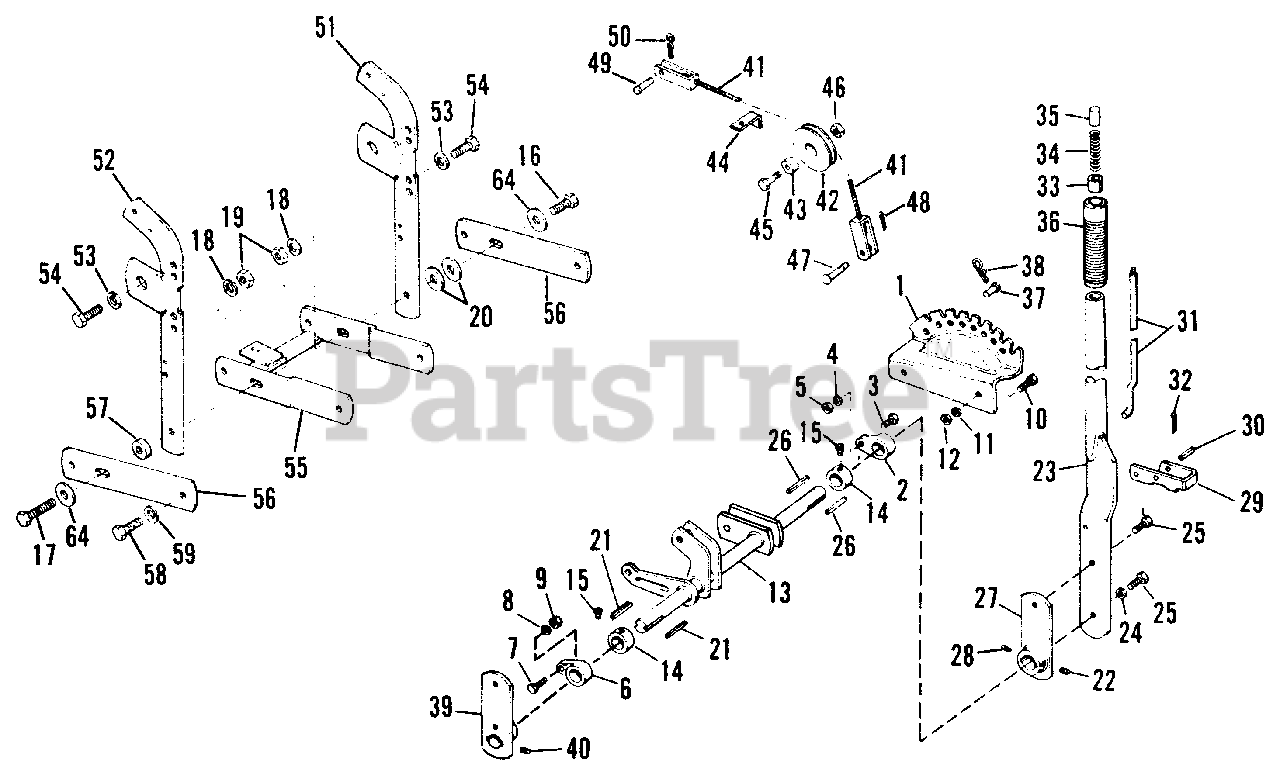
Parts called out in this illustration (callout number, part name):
1	Lift Lever Quadrant
2	Lift Lever Bearing
3	Hex Capscrew, 5/16"-18 x 1-1/4"
4	Lockwasher, 5/16"
5	Full Hex Nut, 5/16"-18
6	Lift Lever Bearing
7	Hex Capscrew, 5/16"-18 x 1-1/4"
8	Lockwasher, 5/16"
9	Hex Nut, 5/16"-18
10	Hex Capscrew, 3/8"-16 x 3/4"
11	Lockwasher, 3/8"
12	Full Hex Nut, 3/8"
13	Lift Shaft Assembly
14	Set Collar
15	Set Screw Sq. Hd., 5/16"-18 x 3/8"
16	Hex Capscrew, 7/16"-14 x 1-1/2"
17	Hex Capscrew, 7/16"-14 x 1-3/4"
18	Lockwasher, 7/16"
19	Full Hex Nut, 7/16"-14
20	Plain Washer, 5/16"
22	Set Screw, 5/16"-18 x 1/4"
23	Lift Lever Assembly
24	Lockwasher, 3/8"
25	Hex Capscrew, 3/8"-16 x 1"
27	Lift Lever Assy. Inner Section
28	Set Screw, 5/16"-18 x 1/4"
29	Lift Lever Latch
30	Roll Pin. 3/8" x 1-1/4"
31	Latch Rod
32	Cotter Pin, 3/32" x 3/4"
35	Thumb Button
36	Handle Grip
38	Spring Clip
39	Front Lift Lever Assembly
40	Set Screw, 5/16"-18 x 1/4"
41	Cable Assembly, Lift
44	Cable Guard
46	Hex Jam Lock Nut, 3/8"-16
47	Pin
48	Cotter Pin, 3/32" x 7/8"
50	Spring Clip
51	Arm Assembly
52	Arm Assembly
53	Lockwasher, 7/16"
54	Hex Capscrew, 7/16"-14 x 1"
55	Draw Bar Assembly
58	Hex Capscrew, 7/16"-14 x 1-1/4"
59	Lockwasher 7/16"
